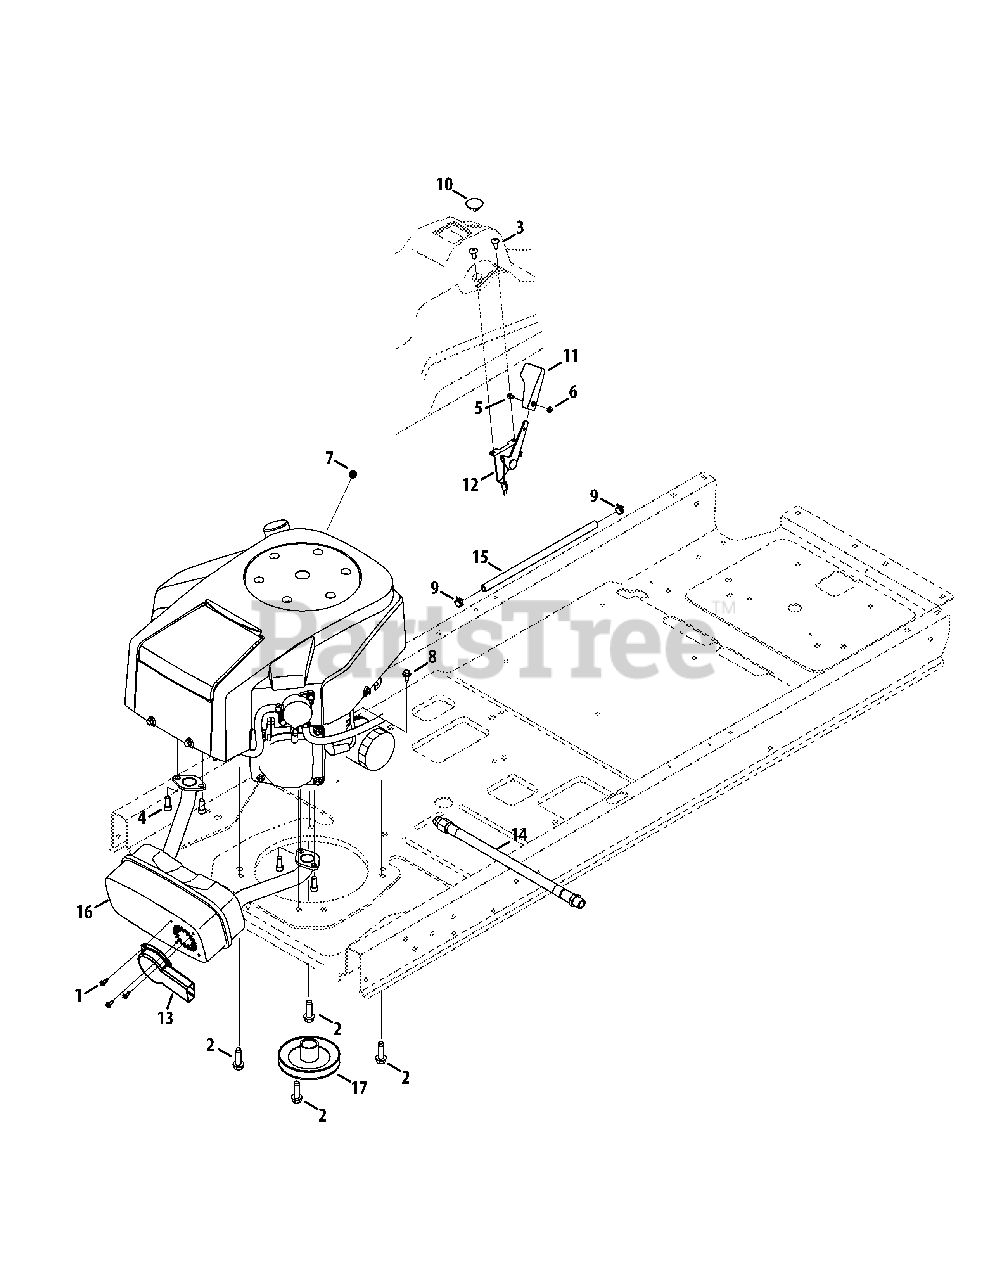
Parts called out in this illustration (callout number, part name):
1	Hex Washer Screw, #8-18 x .500
2	Hex Washer Screw, 3/8-16 x 1.00
3	Screw, 1/4-20 x .50
4	Socket Head Screw, 5/16-18 x .750
5	Screw, #8-32 x .375
6	Hex Nut, #8-32
7	Flange Lock Nut, 1/4-20
8	Hex Washer Screw, 1/4-20 x .625
9	Hose Clamp, .490 Dia.
10	Choke Plug
11	Throttle Control Knob
12	Throttle/Choke Control Cable
13	Muffler Deflector Long
14	Oil Drain Hose
15	Fuel Hose, 1/4
16	Twin Muffler
17	Engine Pulley
